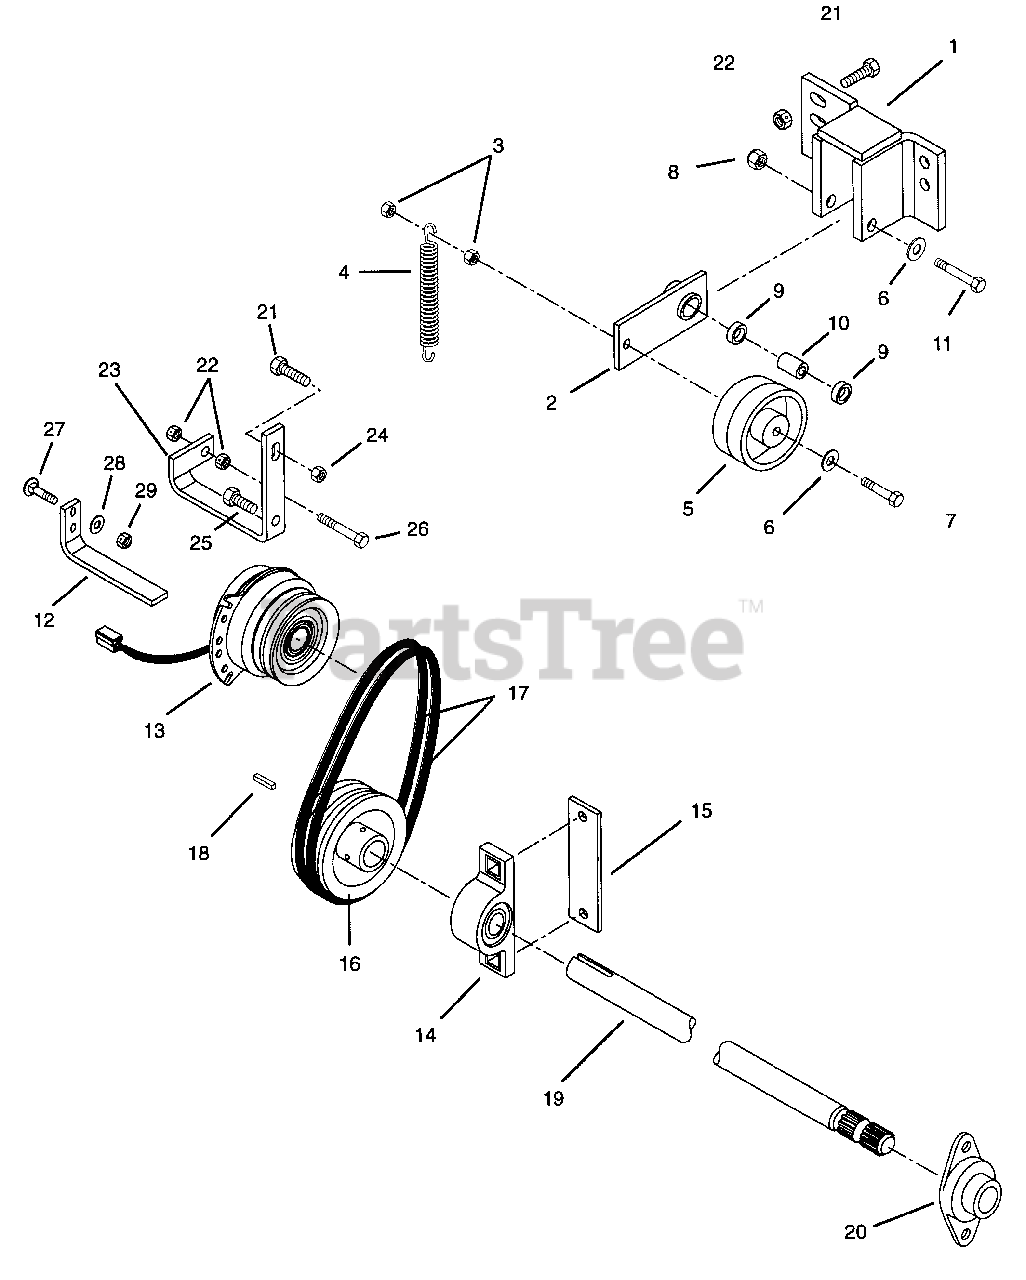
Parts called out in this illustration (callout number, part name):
1	Bracket,Idler Pivot Mount
2	Weldment,PTO Idler Arm
3	Nut-Hex .375-16 Grade 2
4	Spring-Tension .091 x .56 x 5.07
5	Idler-Flat 3.25 x .38
6	Washer-Flat-Steel .406 x .812 x .065
7	Bolt-Hex .38-16 x 1.00 Grade 5
8	Nut-Locking-Nylon .375-16 Grade 2
9	Bushing,Bronze .75ID x .88OD x .5LG
10	Spacer, .38ID x .5OD x 1.5LG
11	Bolt-Hex .38-16 x 1.75 Grade 5
12	Bracket, Clutch Stop PM-350
13	Electric Clutch
14	PillowBlock, 65 Deg.
15	Plate,Bearing Mount
16	Sheave, 2 Groove
17	Belt,Set(2) 4L-Section 34.12 x 17/32
18	Key,Gib .25 x 1.5
19	Shaft, PM-350 PTO Output
20	Bearing, 1" I.D. Flange Mount
21	Bolt-Hex .31-18 x 1.00 Grade 5
22	Nut-Locking-Center .31-18
23	PTO Clutch Stop (003)
24	Nut-Hex .31-18
25	Bolt-Hex M8 x 1.25 x 16MM
26	Bolt-Hex .31-18 x 2.50 Grade 5
27	Bolt-Round head Square neck .25-20 x 1.00
28	Washer-Flat-Steel .312 x .734 x .065
29	Nut-Locking-Center .25-20
